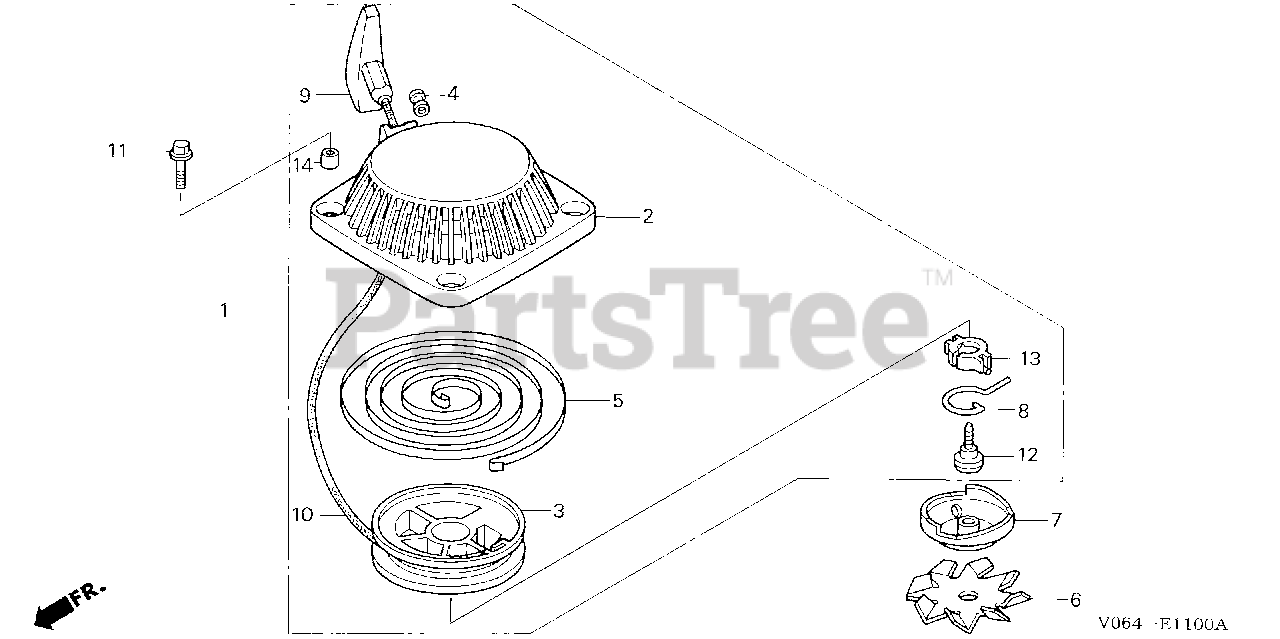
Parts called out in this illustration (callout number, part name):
1	STARTER ASSY., RECOIL *NH1* (BLACK)
2	CASE, RECOIL STARTER
3	REEL, RECOIL STARTER
4	GUIDE, ROPE
5	SPRING, RECOIL STARTER
6	FAN, RATCHET
7	PULLEY, RECOIL STARTER
9	KNOB, RECOIL STARTER
10	ROPE, RECOIL STARTER
11	BOLT, FLANGE (5X18)
12	SCREW, SETTING
